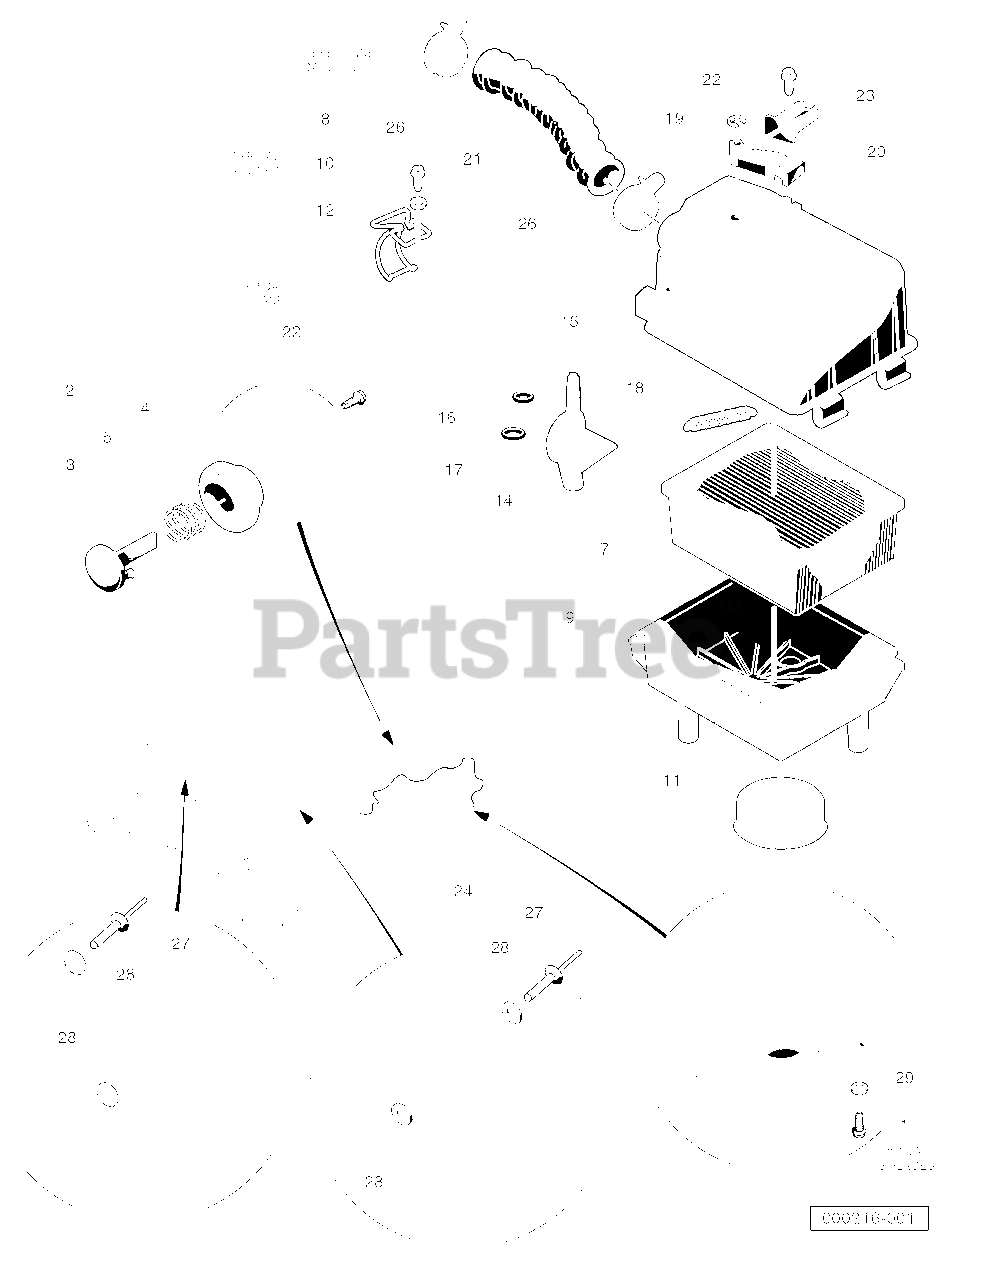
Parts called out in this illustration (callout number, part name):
1	Screw, #12-16 X 0.625 Hi-Lo
2	Button Assembly, Choke
3	Lever, Choke
4	Guide, Choke Lever
5	Compression Spring
6	Assembly, Air Box
7	Filter, Air
8	Screw, #8 X 0.500, Hex-Head Hi-Lo
9	Bottom, Air Box
10	Washer, #8 Stainless-Steel Flat
11	Seal, Intake
12	Latch, Wireform
13	Top Assy, Air Box
14	Valve, Choke
15	Top, Air Box
18	Spring, Extension Return
19	Retaining Ring 0.25, Shaft
20	Lever, Choke
21	Hose, Air Intake
22	Screw, #12-16 X 0.50 Washer-Head Hi-Lo
23	Choke Positioner
24	Duct Assembly
26	Clamp, 1.58" ID Hose
27	Rivet, 3/16 X .500 Alum Pop
28	Washer, #10 Type A Flat
29	Washer, 1/4 Type A Narrow Flat
